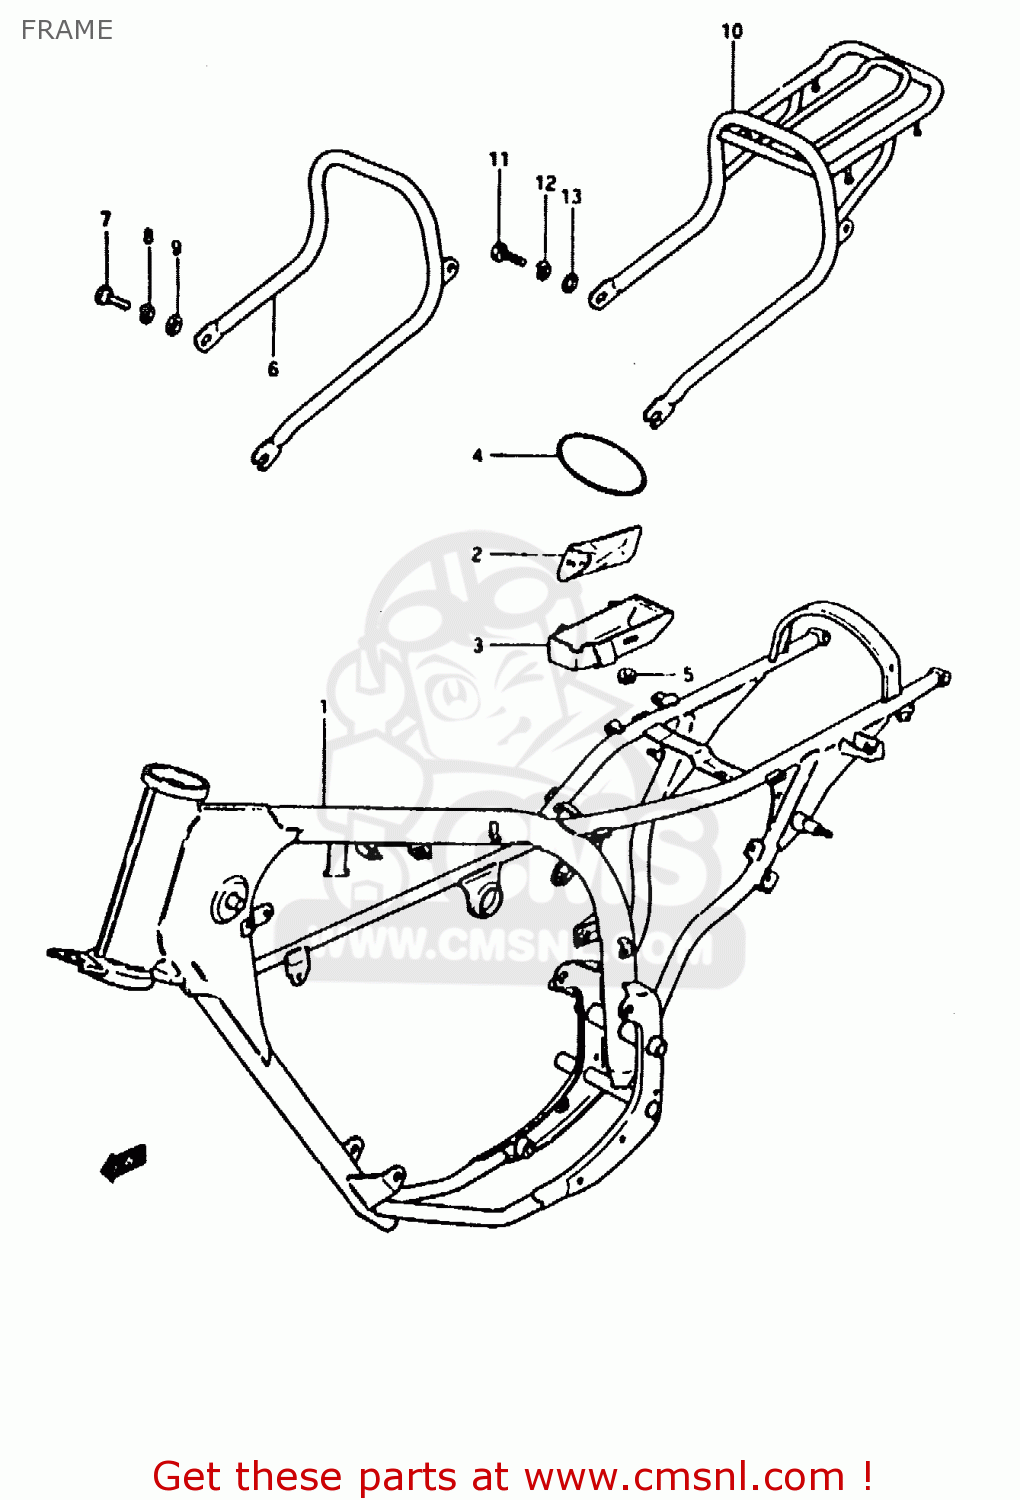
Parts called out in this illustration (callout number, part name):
1	FRAME (BLACK)
2	TOOL ASSY
3	HOLDER, TOOL
4	O RING(D:3.5,ID:76)
5	CUSHION
10	CARRIER,SPORT
11	BOLT
12	LOCK WASHER
13	WASHER
